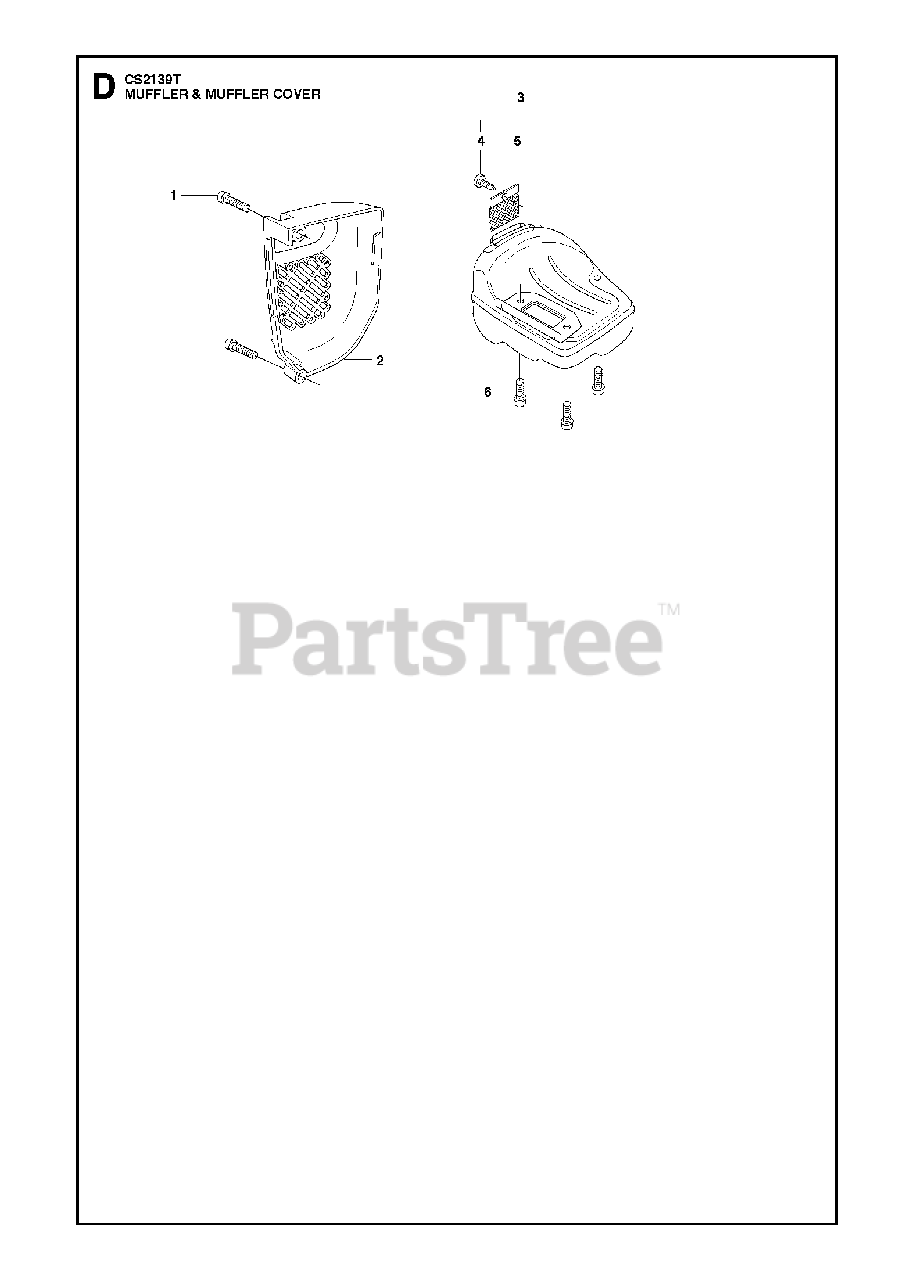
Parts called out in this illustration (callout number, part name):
2	MUFFLER COVER
4	SCREW
5	SCREEN
